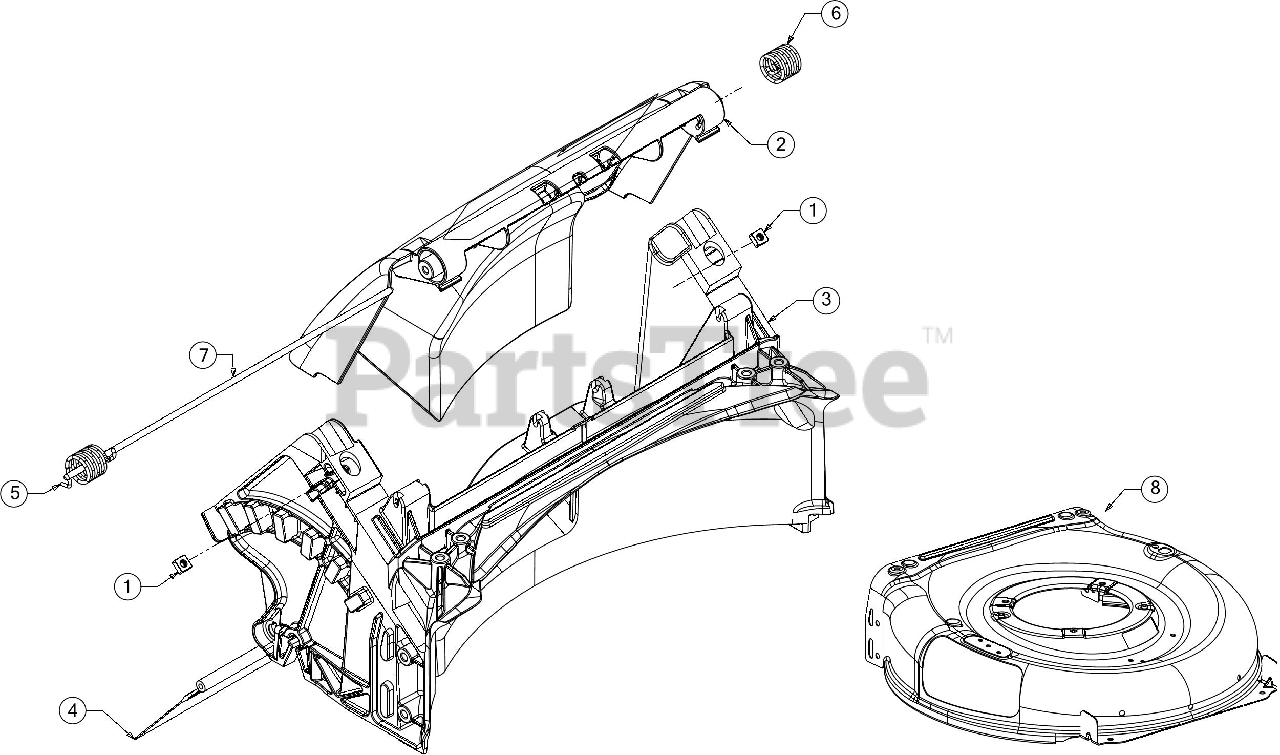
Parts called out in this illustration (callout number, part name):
1	SQUARE NUT 1/4-20
3	DOOR ASSEMBLY
4	TRAILSHIELD
5	TORSION SPRING (RH)
6	TORSION SPRING (LH)
7	REAR DOOR PIVOT ROD
8	21" DECK (3N1)
